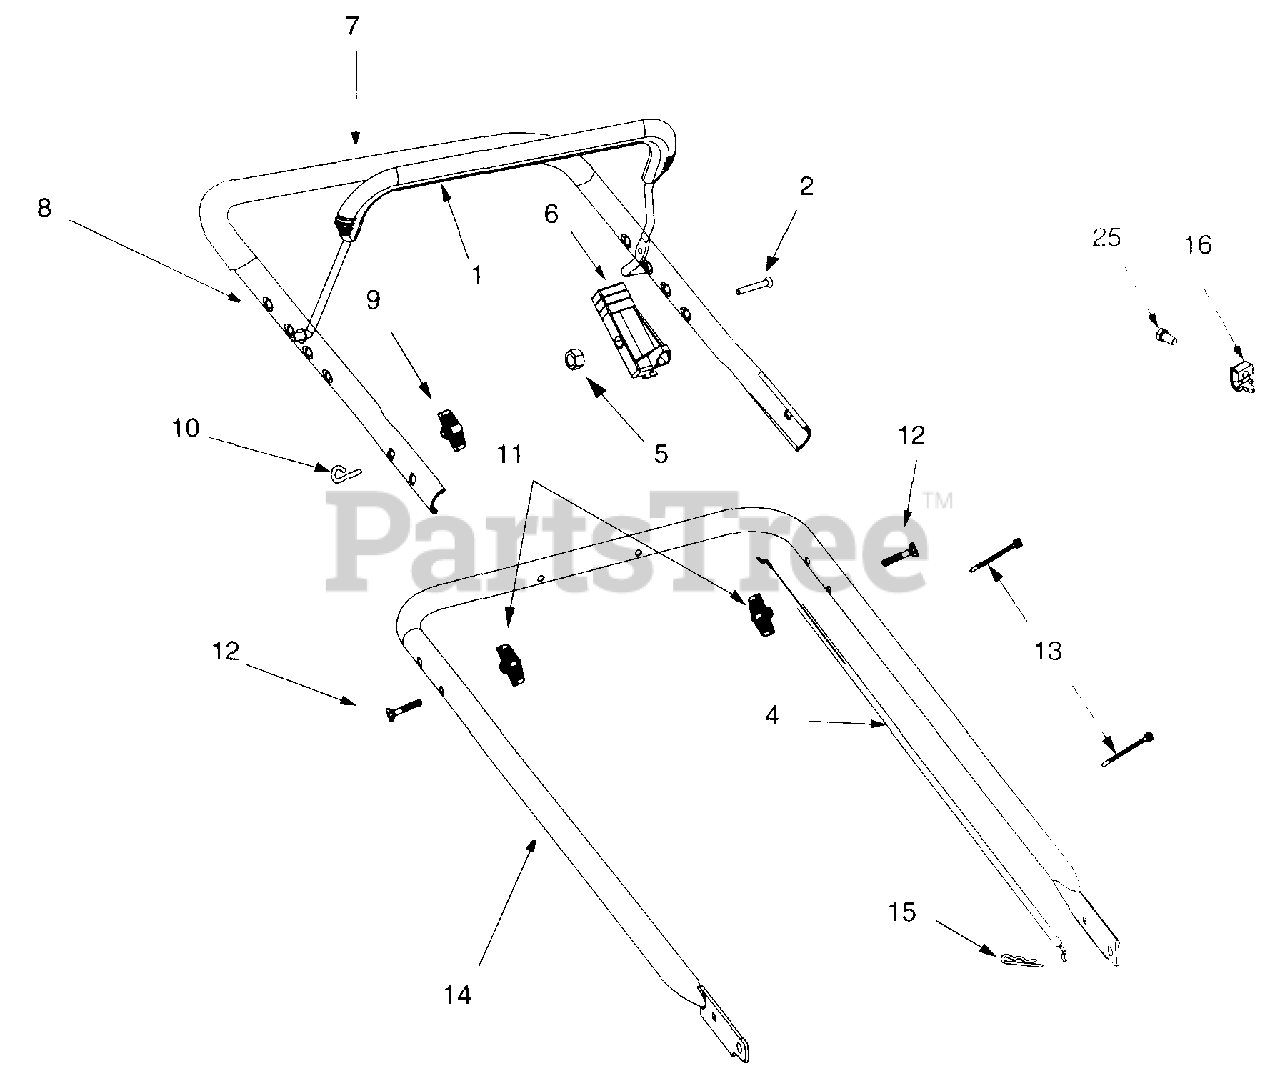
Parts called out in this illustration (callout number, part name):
1	Control Handle Ass'y.
2	Screw, 1/4-20
4	Control Cable 36"
5	Hex Lock Nut
6	Throttle Housing
7	Foam Grip, 22"
10	Rope Guide
11	Hand Knob
12	Carriage Bolt
13	Cable Tie
15	Hairpin Clip
